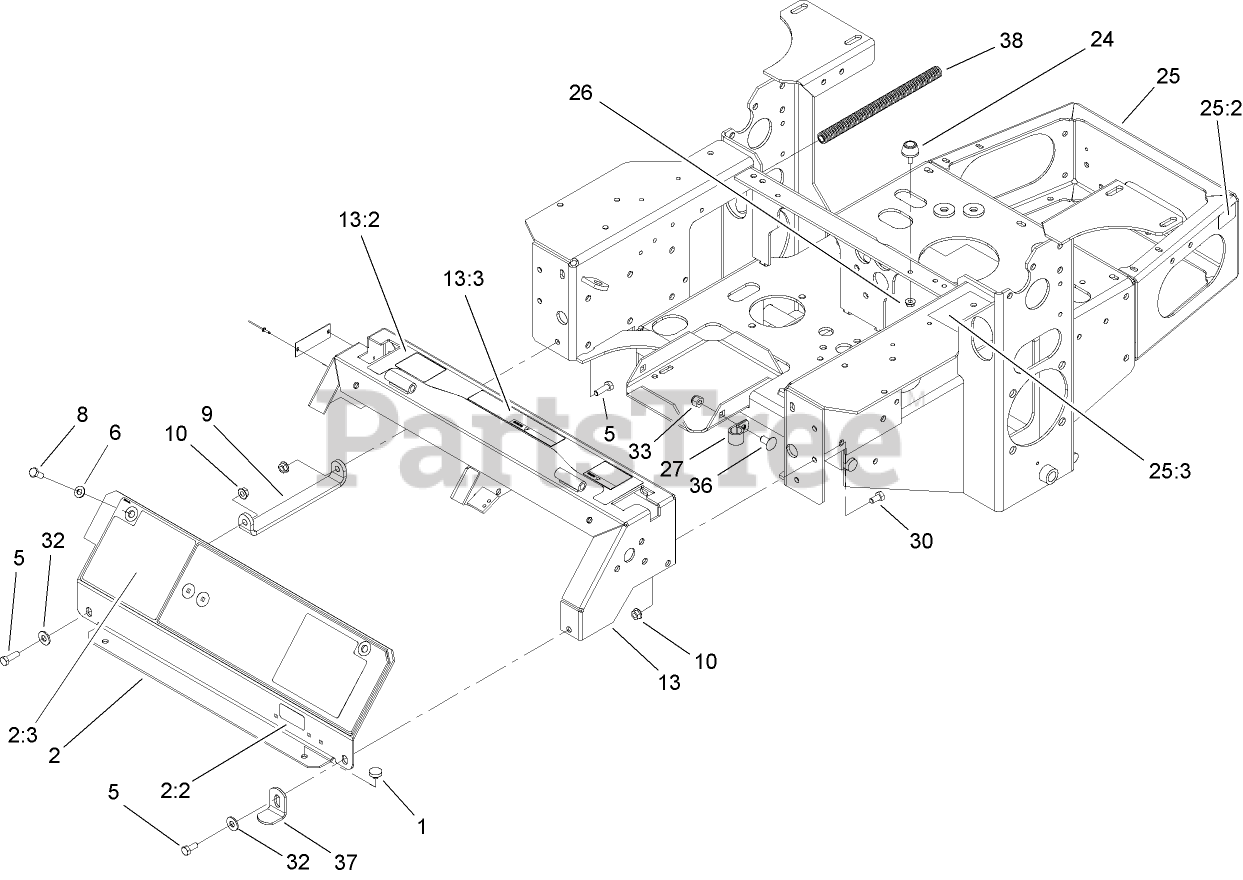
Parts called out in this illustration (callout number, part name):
1	BUMPER
2	PANEL ASM
2:2	DECAL-PROTECTION, EAR
2:3	DECAL-PANEL, COVER
5	SCREW-HH
6	WASHER-PLAIN
8	SCREW-HH
9	BRACKET-PANEL, INSTRUMENT
10	NUT-HF
13	CONSOLE
13:2	DECAL-CONTROL, MOTION
13:3	DECAL-BATTERY
24	BUMPER
25	MAIN FRAME ASM
25:2	DECAL-WARNING
25:3	Decal-Release, Drive
26	NUT-HF
27	CLIP-LOOM
30	SCREW-HH
32	WASHER-FLAT
33	NUT-LOCK, NI
36	SCREW-CARR
37	STOP-COVER
38	CONDUIT-CONVOLUTED, SPLIT
